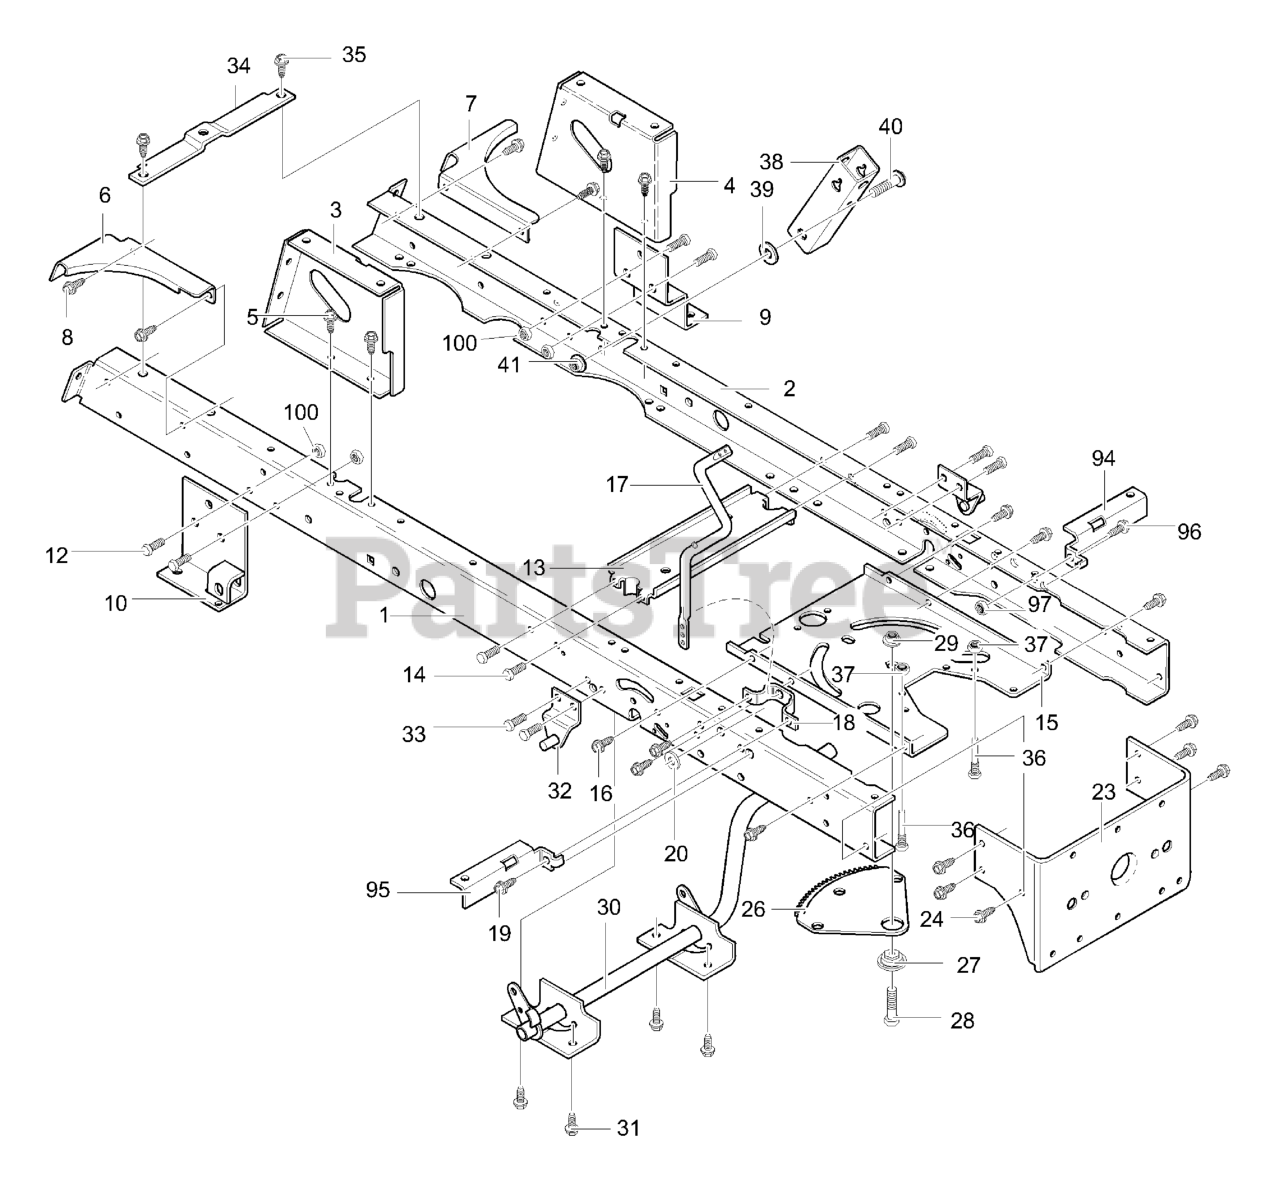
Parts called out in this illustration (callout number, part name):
1	Frame, Rail RH
2	Frame, Rail LH
3	Support, Seat RH
4	Support, Seat LH
5	Screw, .312-18x.75
6	Brace, Right Back Plate
7	Brace, Left Back Plate
8	Screw, 5/16-18 x 0.75
9	Bracket, Right Transaxle
10	Assy., Shift Brace
12	Screw, .312-18x.75
13	Assy., Idler Mount, Front
14	Screw, .312-18x.75
15	Plate, Steering
16	Screw, .312-18x.75
17	Crank, PTO
18	Bracket, Bell Crank
19	Screw, .312-18x.75
20	Washer, Flat
23	Bracket, Hanger Rear
24	Screw, .312-18x.75
26	Gear, Sector
27	Bearing, Sector Gear
28	CAPSCREW, Hex Head, 5/16-18 x 1
29	Nut, 5/16-18
30	Clutch/Brake Pedal
31	Screw, .312-18x.75
32	Assembly, Suspension Bracket
33	Screw, .312-18x.75
34	Brace, Rail
35	Screw, .312-18x.75
36	Zinc Screw Guide
37	Nut, 5/16-18
38	Bracket, Pivot
39	Washer, Flat
40	Bolt, Shoulder 3/8-16
41	Nut, 3/8-16
94	Bracket, Left Seat Deck
95	Bracket, Right Seat Deck
96	Screw, .312-18x.75
97	Nut, 5/16-18
100	Nut, 5/16-18
